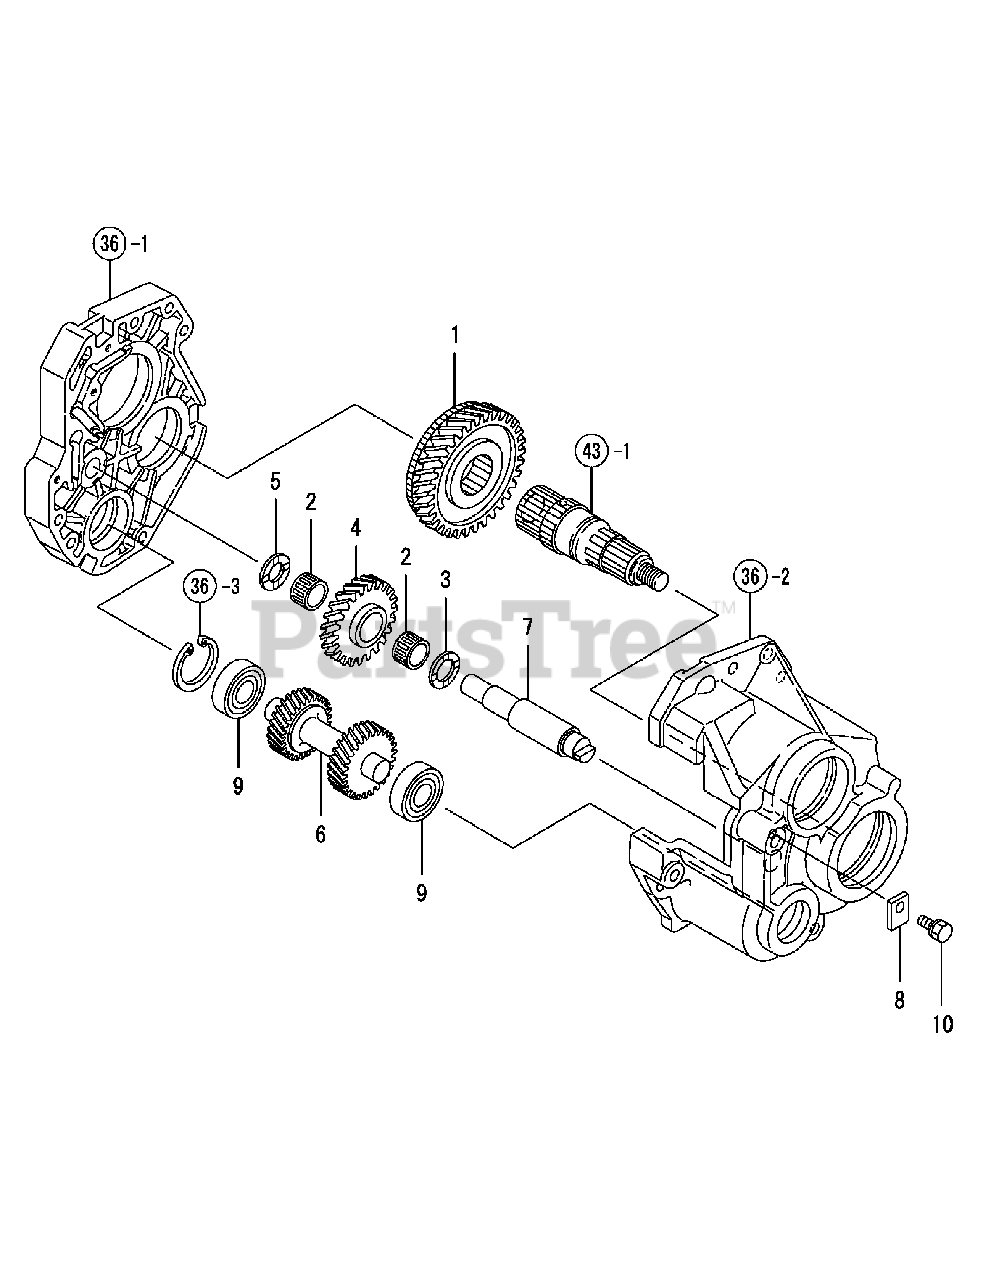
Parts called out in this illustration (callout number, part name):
3	WASHER,SRAST 20X32X2
5	SLAST WASSHER 17X32
9	BALL BEARING #6204
10	BOLT W/WASHER M8X20
